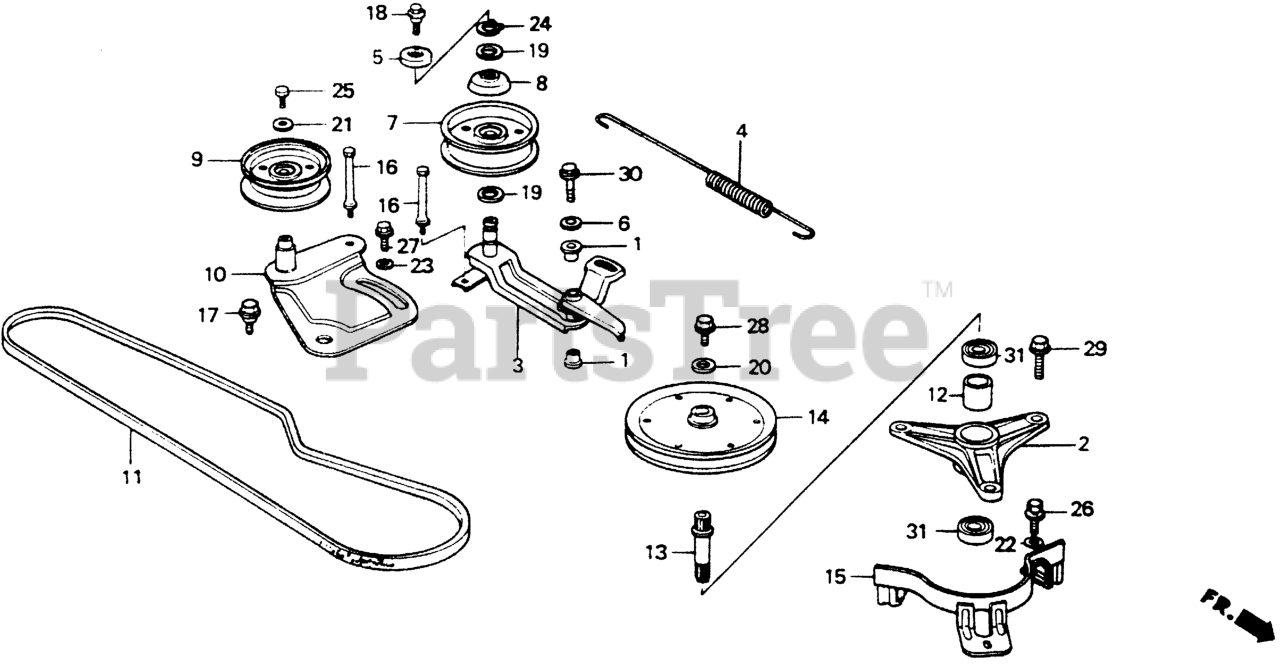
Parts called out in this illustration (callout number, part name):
1	BUSH (15X19X22)
2	HOUSING, BEARING (NOT AVAILABLE)
3	ARM, TENSION (DECK) (NOT AVAILABLE)
4	SPRING, TENSIONER ARM
5	GRIP, TENSION ARM (NOT AVAILABLE)
6	CAP, TENSION ARM
7	ROLLER, TENSIONER
8	DUST COVER, TENSION PULLEY (NOT AVAILABLE)
9	PULLEY, TENSIONER
10	ARM, BELT ADJUSTING
11	V-BELT, BLADE (SB-70)
12	COLLAR, BLADE SHAFT
13	SHAFT, BLADE
13	SHAFT, BLADE (112.5MM)
14	PULLEY, CUTTER DECK (120MM)
15	COVER, DECK PULLEY
16	BOLT, BELT STOPPER
17	BOLT, ADJUSTING ARM
18	BOLT, FLANGE (6MM)
19	WASHER (17.3X25)
20	WASHER (10.3MM)
21	WASHER, PLAIN (6MM)
22	WASHER, PLAIN (6MM)
23	WASHER, PLAIN (8MM)
24	CIRCLIP (OUTER) (17MM)
25	BOLT, FLANGE (6X12) Use up to Engine SN 1543277.
26	BOLT, FLANGE (6X16)
27	BOLT, FLANGE (8X16) Use from Engine SN 1000016.
28	BOLT, FLANGE (10X16)
29	BOLT, FLANGE (10X30)
30	BOLT, FLANGE (6X12) Use from Frame SN 1001725.
31	BEARING, RADIAL BALL (6204UU)
